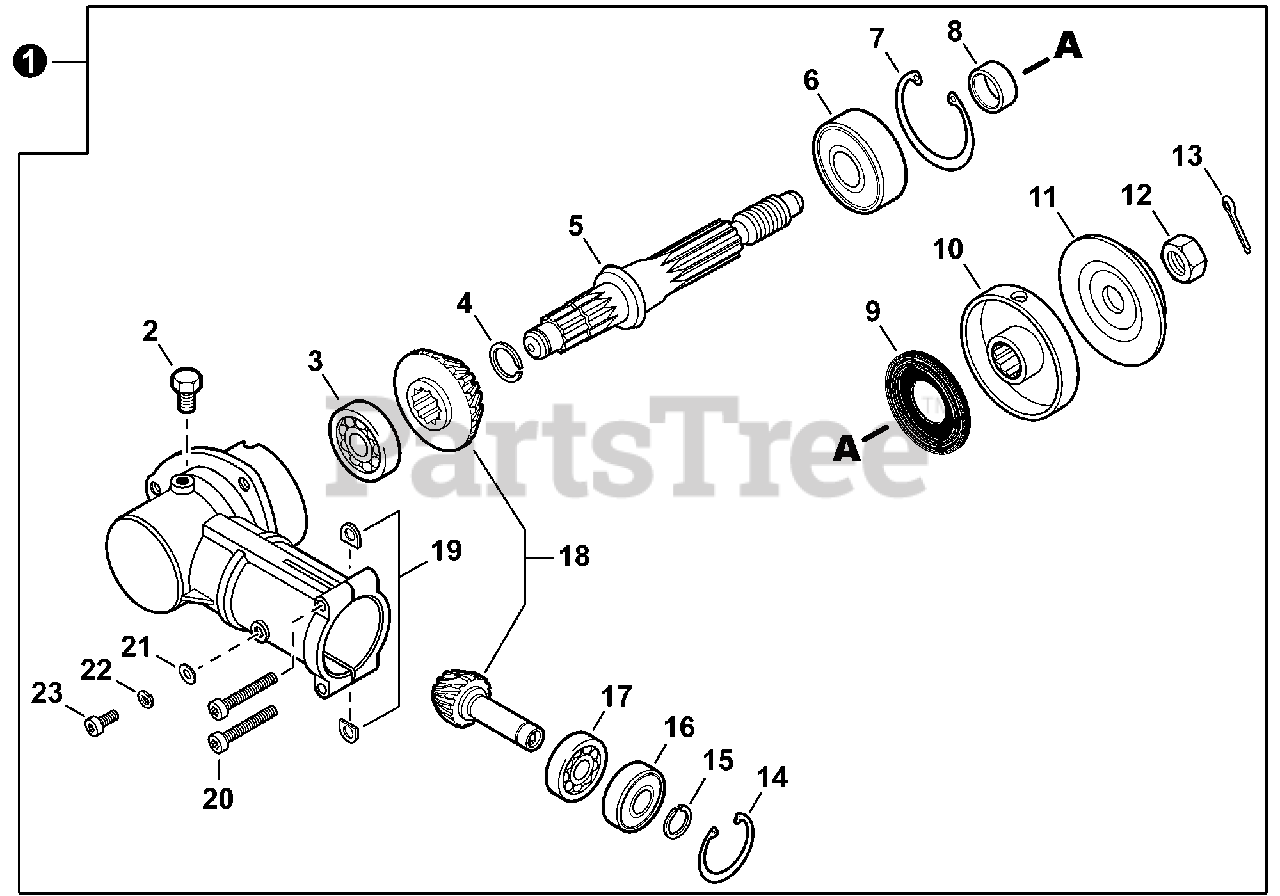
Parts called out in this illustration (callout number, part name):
1	GEAR CASE ASSY
2	BOLT M8×8
3	BEARING, BALL 609
4	RING, SNAP Ø12
5	SHAFT, GEAR
6	BEARING, BALL 6201
7	RING, SNAP Ø32
8	SPACER 11.8×15×9
9	SEAL, OIL 22
10	PLATE, ADAPTOR - UPPER
11	PLATE, ADAPTOR - LOWER
12	NUT 10×1.25 LH
13	PIN, COTTER 2×22
14	RING, SNAP Ø22
15	RING, SNAP Ø10
16	BEARING, BALL 6900-Z
17	BEARING, BALL 6900
18	GEAR SET
19	D-WASHER
20	BOLT, TORX 5×25
21	WASHER, FLAT 5.5×10×0.8
22	WASHER, SPRING 5
23	BOLT, TORX 5×12
